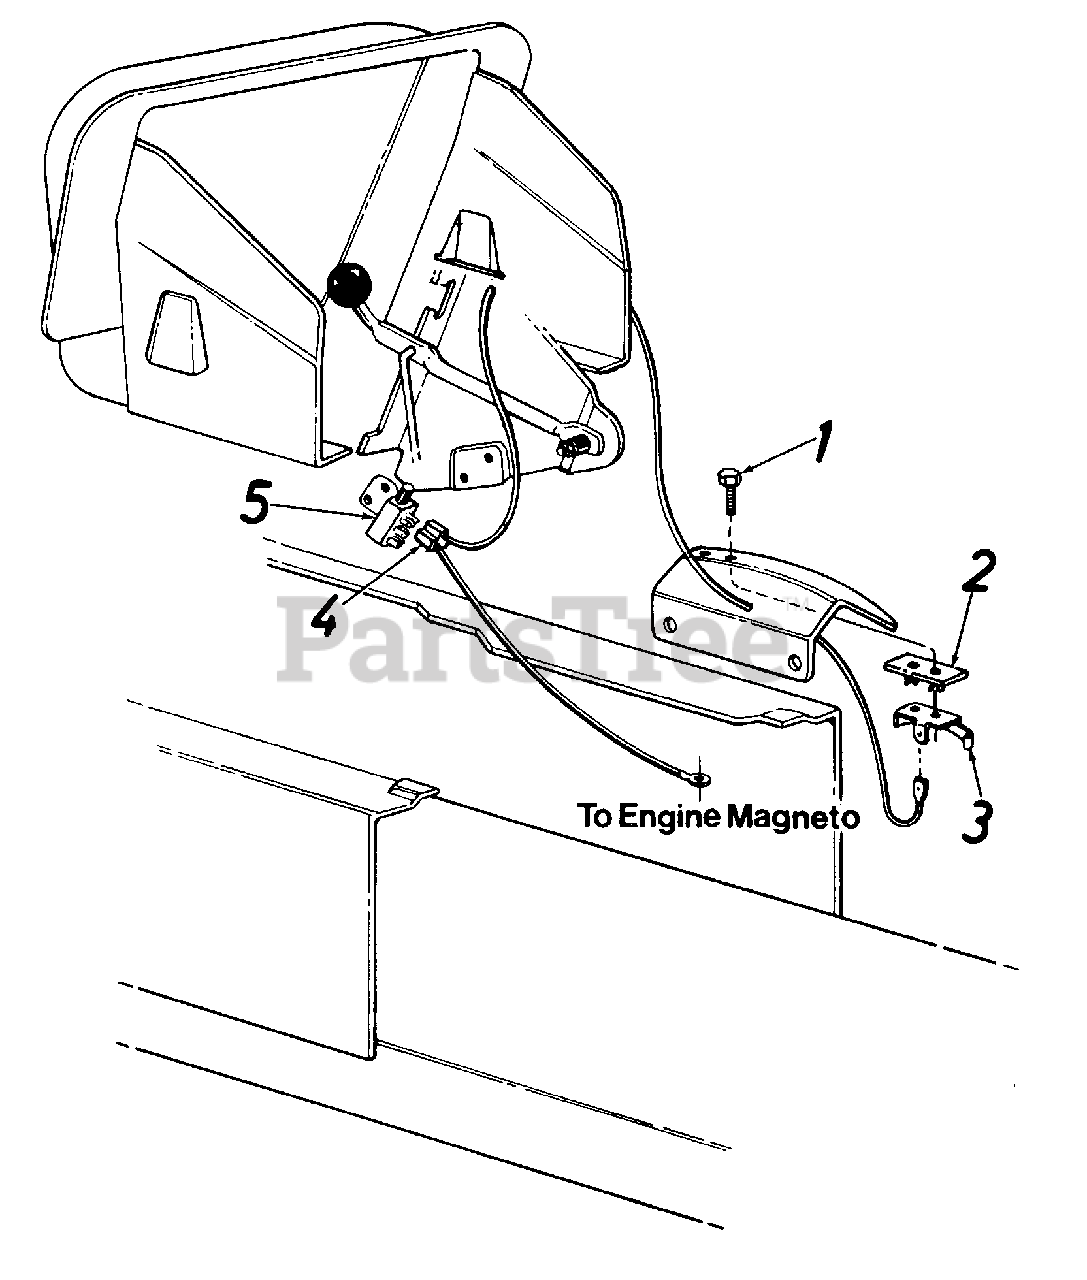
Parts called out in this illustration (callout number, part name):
1	Hex Wash. Hd. Screw #8 x .50" Lg.
2	Insulator Nut Plate
3	Spring Switch
4	Reverse Lockout Wire Harness
5	Safety Switch
